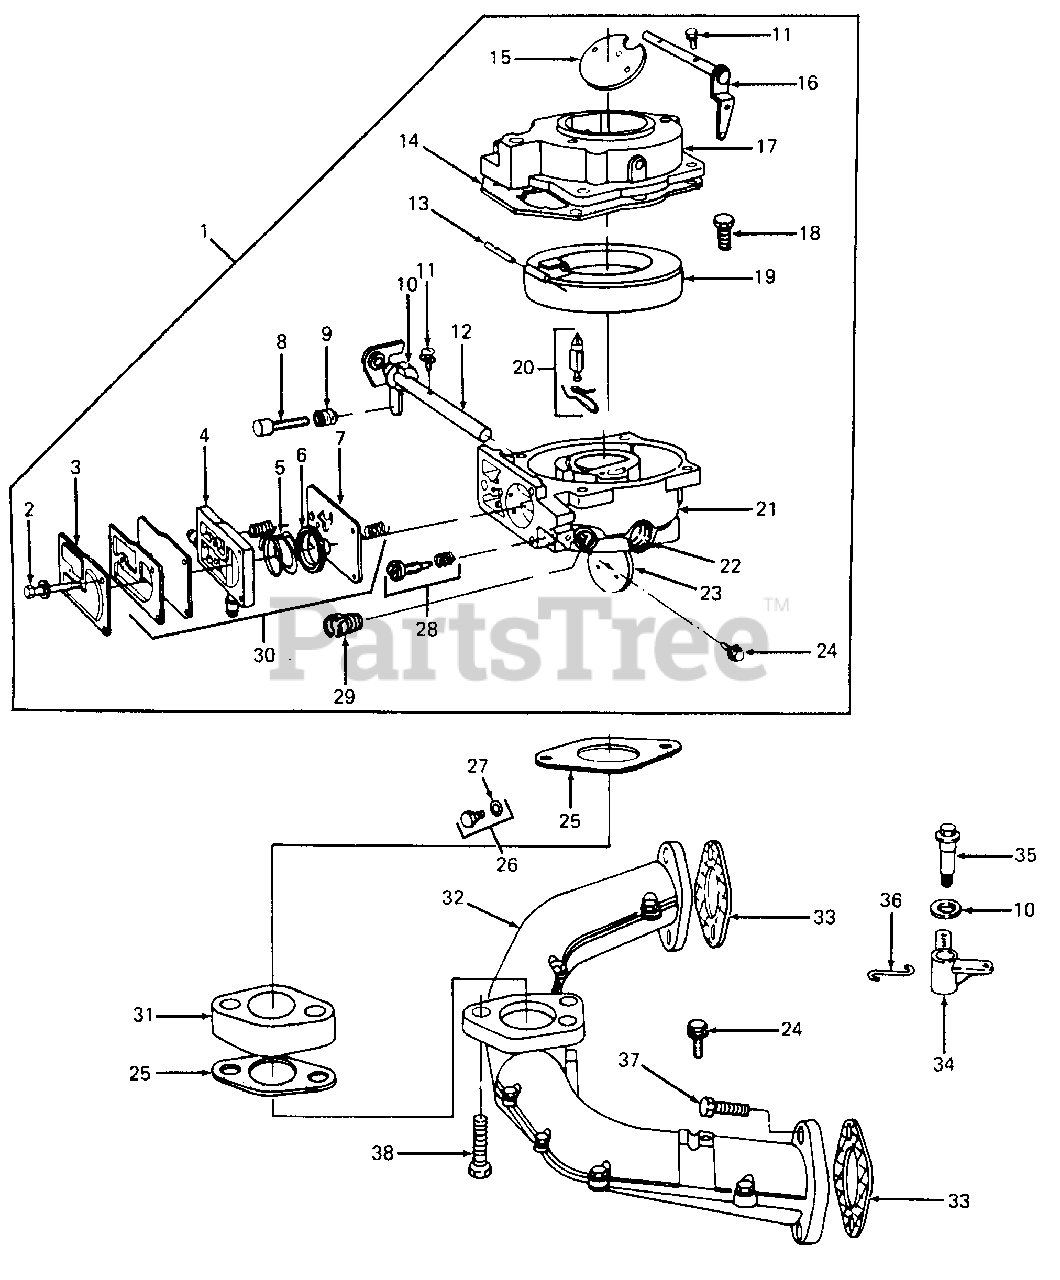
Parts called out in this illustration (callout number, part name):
1	Carburetor Assembly
2	Screw, Diaphragm Cover
3	Cover, Diaphragm
4	Body, Pump
5	Spring, Pump
6	Cap, Spring
8	Screw, Machine Fill Hd 8-32 X 5/8
9	Spring, Throttle Adjustment
10	Washer, Throttle Shaft
11	Screw, Throttle & Choke Valve Mtg Sem
12	Shaft & Lever Throttle
13	Pin, Float Hinge
14	Gasket, Carburetor Body
15	Valve, Choke
16	Shaft & Lever, Choke
17	Body Assy, Upper Carburetor
18	Screw, Hex Hd Sem
19	Float, Carburetor
20	Valve, Fuel Inlet
21	Body, Lower Carburetor
22	Bushing, Throttle Shaft
23	Valve, Throttle
24	Screw, Sem
25	Gasket, Carburetor & Intake Elbow
26	Plug & Seal, Solenoid
28	Valve Assy, Carburetor Idle
29	Jet, Needle Valve
30	Repair Kit, Pump
31	Spacer, Carburetor
32	Manifold Assy, Intake
33	Gasket, Intake Manifold Mtg
34	Crank, Bell
35	Screw, Hex Hd
36	Link, Throttle
37	Screw, Intake Manifold Mtg Sem
38	Screw, Hex Head, Carburetor to Manifold
